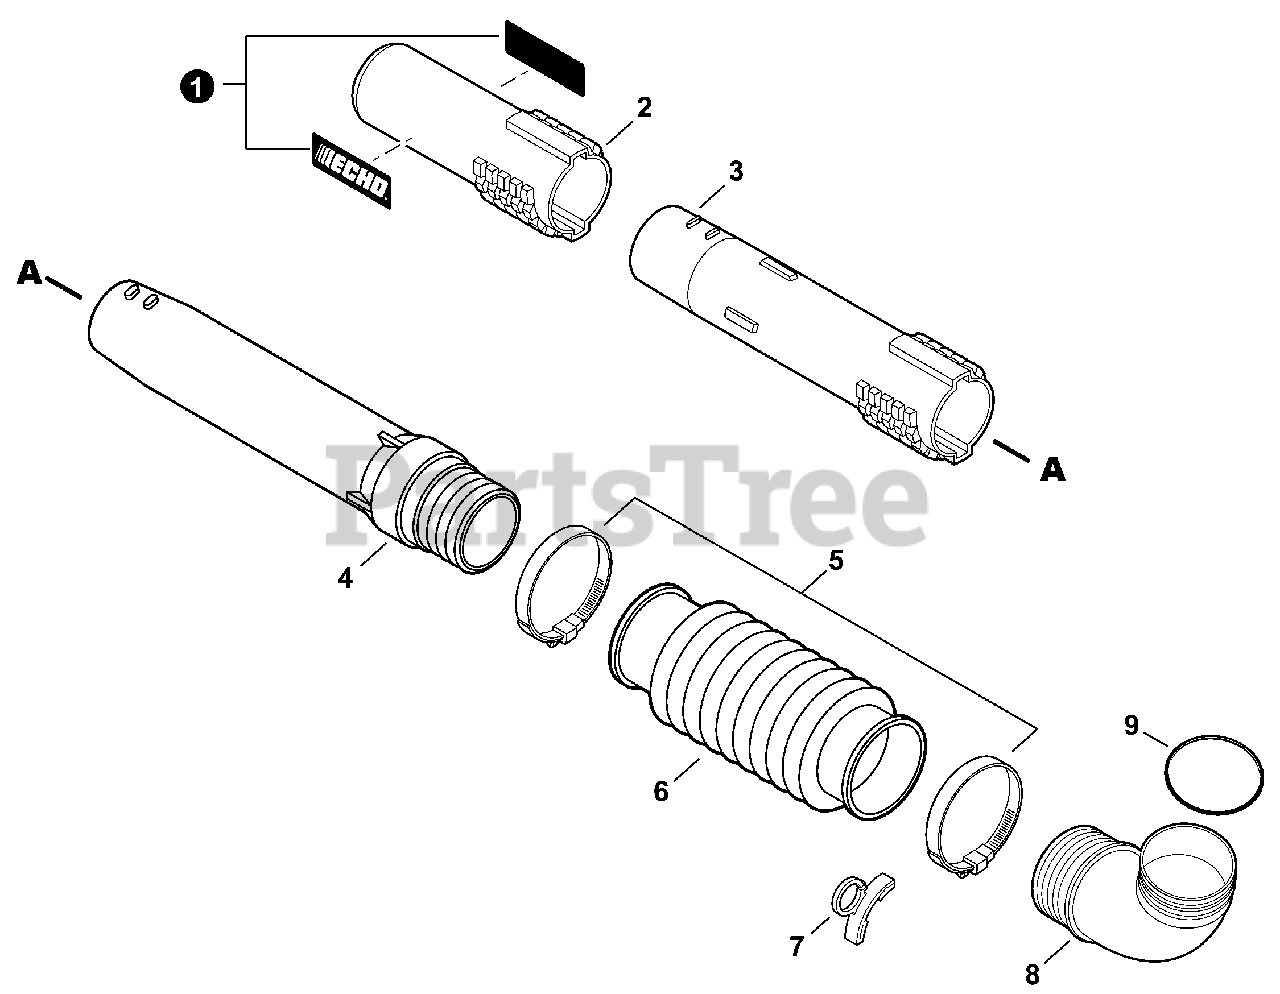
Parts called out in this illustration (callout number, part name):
1	LABEL, ECHO BLOWER TUBE
2	TUBE, BLOWER - NOZZLE
3	TUBE, BLOWER - STRAIGHT
4	TUBE, BLOWER - SWIVEL
5	CLAMP - BAND
6	TUBE, BLOWER - FLEXIBLE
7	CLIP, CABLE
8	TUBE, BLOWER - ELBOW
